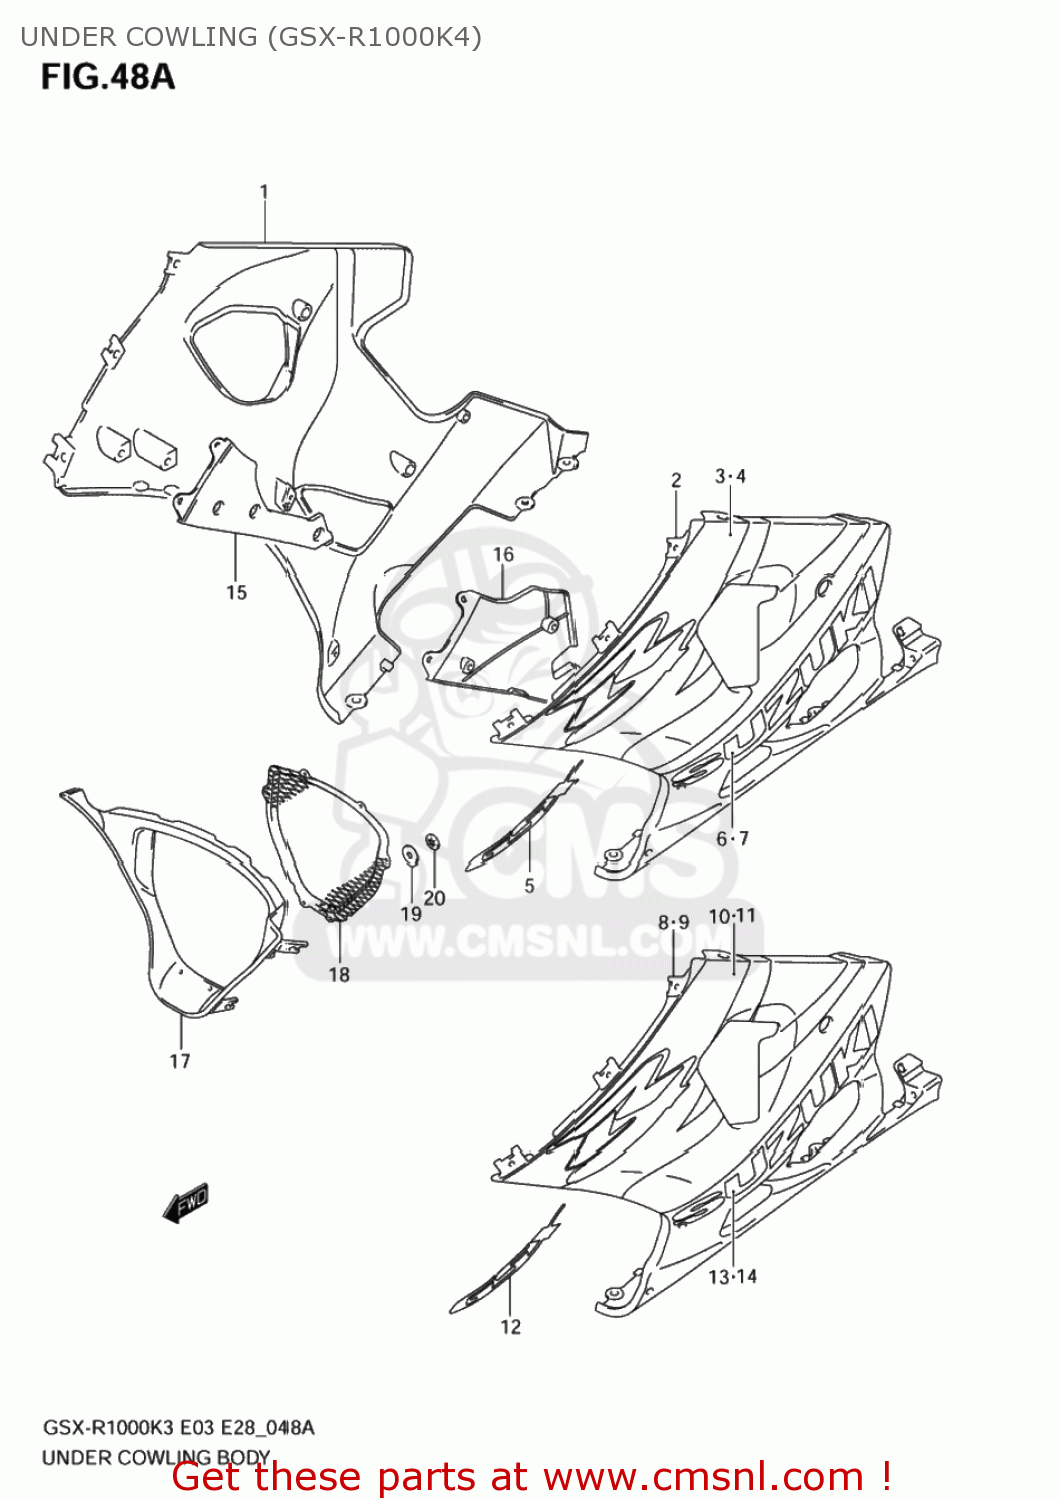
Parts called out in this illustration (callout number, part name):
1	COWLING ASSY,UNDER,R
2	COWLING ASSY,UNDER,L
3	TAPE SET,COWL UNDER,R
4	TAPE SET,COWL UNDER,L
5	EMBLEM,GSX
6	EMBLEM,SUZUKI,R
7	EMBLEM,SUZUKI,L
8	COWLING ASSY,UNDER,R
9	COWLING ASSY,UNDER,L
10	TAPE,COWL UNDER,R
11	TAPE,COWL UNDER,L
12	EMBLEM,GSX
13	EMBLEM,SUZUKI,R
14	EMBLEM,SUZUKI,L
15	COWLING,UNDER INNER,R
16	COWLING,UNDER INNER,L
17	COWLING,UNDER CTR
18	COWLING,UNDER CTR
19	CUSHION
20	NUT
